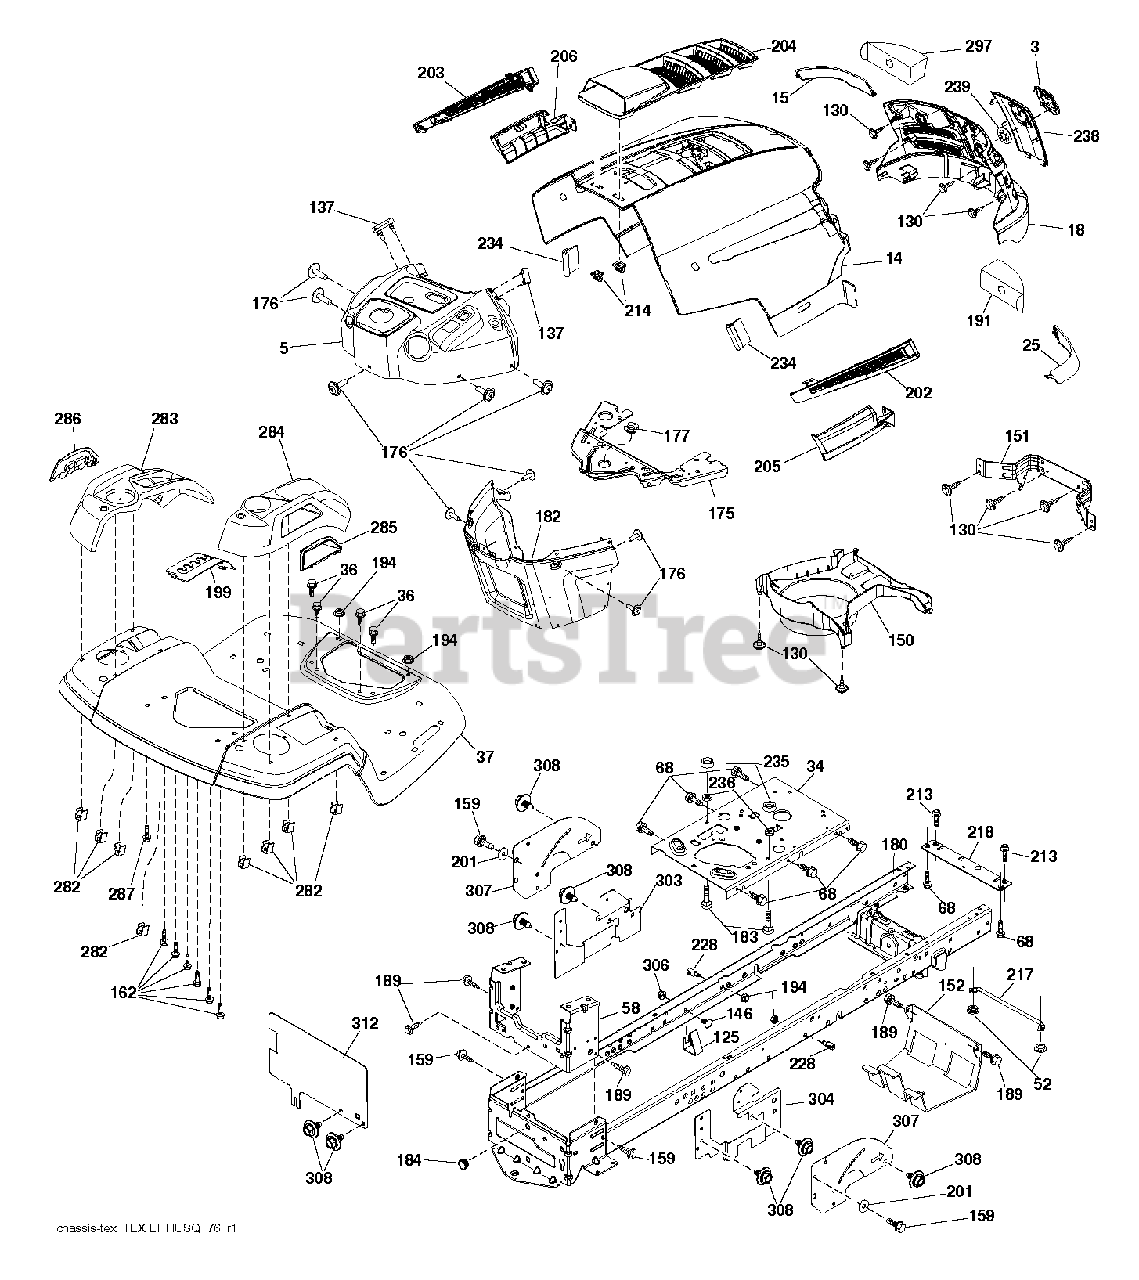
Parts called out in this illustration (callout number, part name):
3	LOGO.HUSQ.GT.LT.CROWN.H
5	DASH.HUSLT.PTO.RS.CHG.SRV.498
14	HOOD.HUSQVARNA.LT.ORANGE
15	LENS.HUSQVARNA LT.RH
18	GRILLE.SVC.HUSQVARNA.GREY
25	LENS LH
34	PLATE.ENGINE.WELDED.CHASSIS
36	SCREW 5/16"
37	FENDER.TLT.FS.W/CUPHLD.ORANGE
52	LOCKNUT
58	DRAWBAR UPPER 2PC SMALL FENDER
68	SCREW LT
125	CLIP.FUEL.LINE
130	SCREW.#10 X 0.750.BOS
137	BUMPER DASH
146	BOLT.RDHD.SHT.SQNK.3/8-16X5/8
151	BRACKET PIVOT
152	SHIELD.BROWNING.W/TEX
159	SCREW, 3/8-16X3/4
162	SCREW.HI-LO.CONSOLE
175	CROSSMEMBER
176	SCREW.#10-24X5/8.RN.QU
177	BUSHING STEERING
180	CHASS.WLDMNT.TLT.12GA/2PC.20"
182	DASH.LOWER.PREDATOR LT
183	BOLT.5/16-18X1-1/4 FULL THD
184	PLUG.DEMO.625
189	SCREW
191	INSERT.REFLECTIVE.RH.
194	NUT LOCK HEX FLANGE 5/16-18
199	PLATE.DECK.LIFT.HUSQ.LT
201	WASHER
202	VENT.SIDE.HUSQVARNA.LT.RT
203	VENT.SIDE.HUSQVARNA.LT.LFT
204	SUBASM.TOP.VENT.HUSQ.LT
205	SKIRT.SIDE.HUSQVARNA.LT.RT
206	SKIRT.SIDE.HUSQVARNA.LT.LEFT
213	BOLT
214	CLIP.RETAINER.TINNER.
217	ROD.PIVOT.HOOD
218	X-PIECE.HOOD.STOP.NON/
228	STUD.FASTNER.W/ANTI-ROTATE
234	BUMPER.HOOD.TEX.HUSQVARNA
235	SPACER FENDER
236	NUT.CENTERLOCK.5/16-
238	TRIM.HUSQ LT.668
282	CLIP.RETAINER.CONSOLE.LT.HUSQ
283	CONSOLE.ASM.LFT.RSF.HUSQ.LT
284	CONCOLE.CNTRL.PDL.HUSQ.LT.498
285	CONSOLE INSERT RH
286	CONSOLE.INSRT.LH.HUSQ.LT.BLACK
287	SCREW 1/4X20
297	INSERT REFLECTIVE
303	SHIELD.LOWER.LH/LT/GT/BLK.EDIP
304	SHIELD.LWR.RH.LT30DECK.PNT.BLK
306	NUT LOCK FLG 3/8-16 UNC
307	SHIELD.UPPER.LT.GT.ISO
308	BOLT, 5/16-18 X 1 3/4
312	SHIELD.PNT.DRAWBAR.FRENCH
